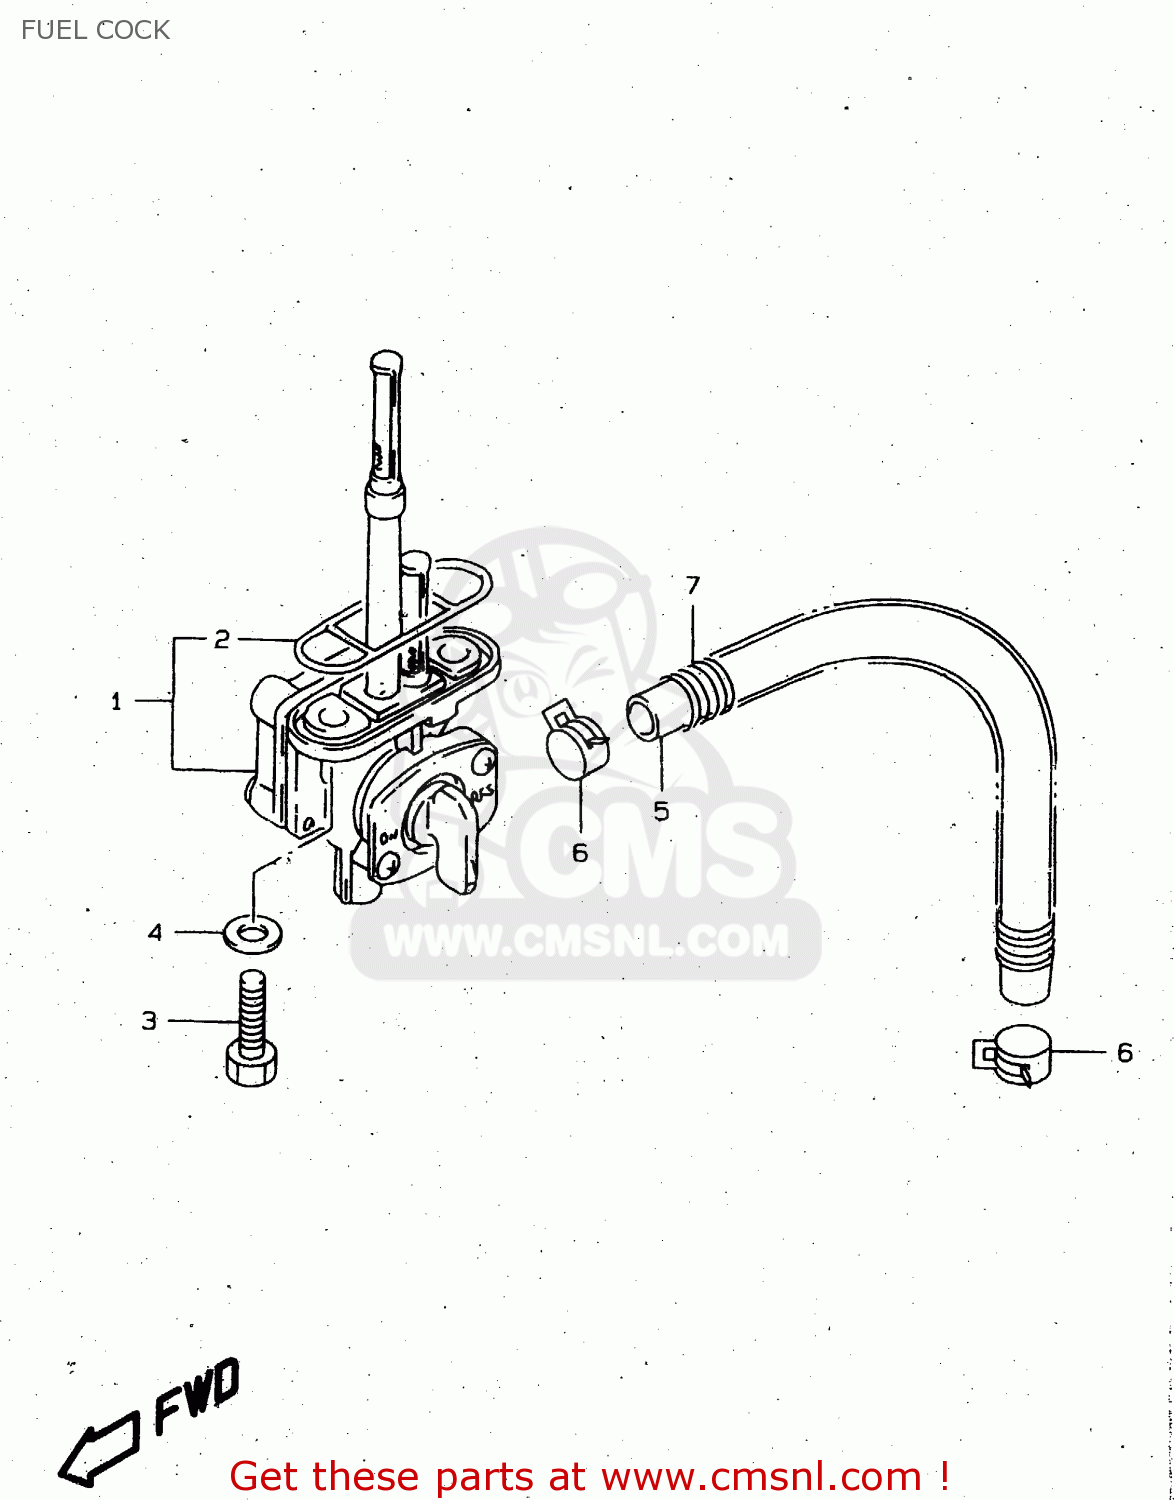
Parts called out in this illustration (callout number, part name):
1	COCK ASSY,FUEL
2	GASKET,JOINT (NAS)
3	BOLT(6X20)
4	GASKET(6.4X11.5X0.8) (NAS)
5	HOSE(7X12X600)
6	CLIP
7	SPRING
